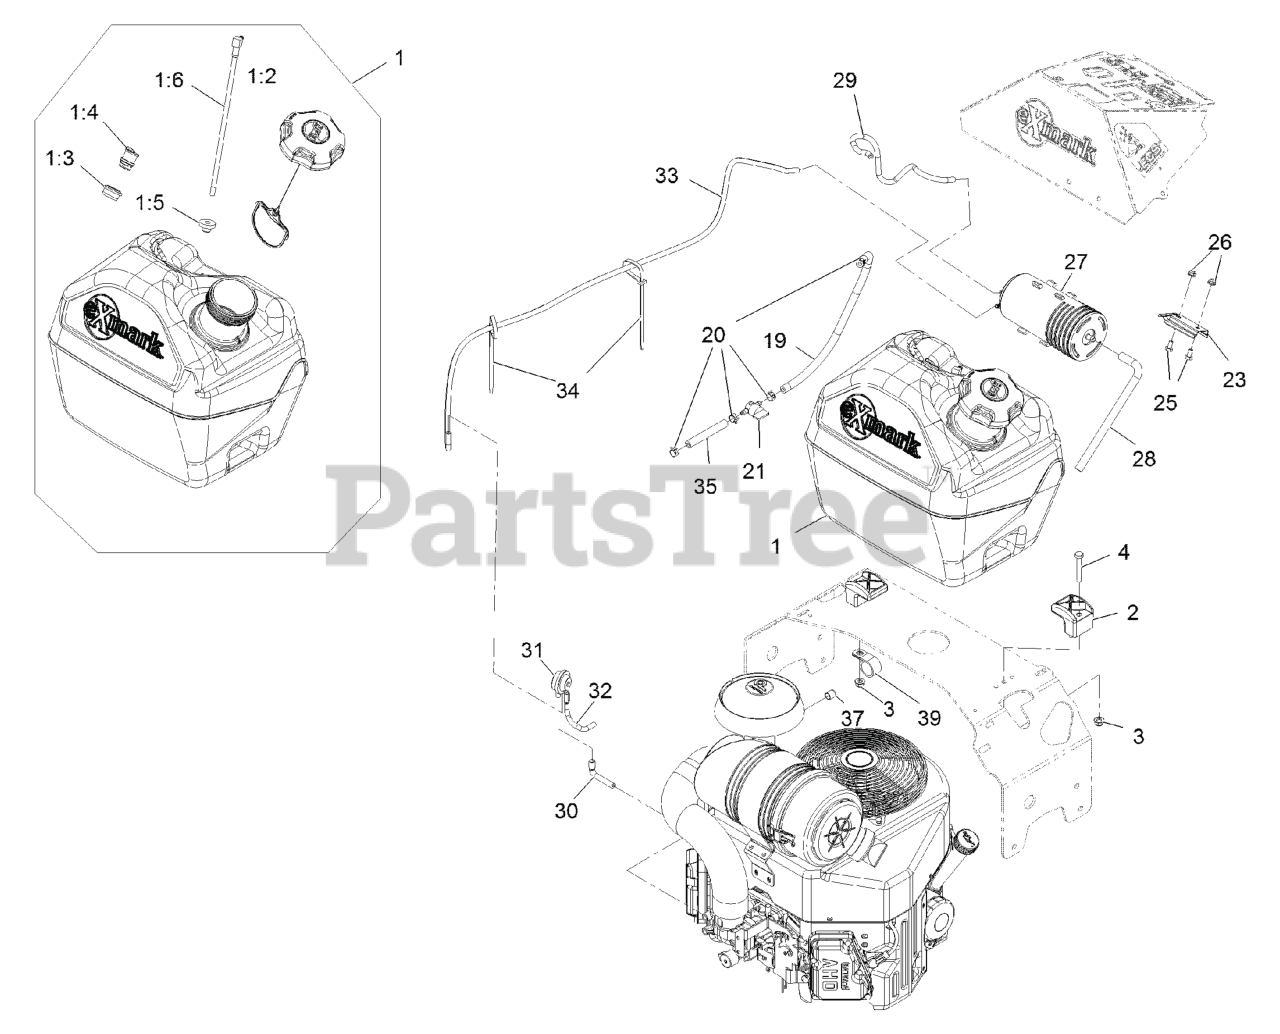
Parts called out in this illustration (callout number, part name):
1:2	CAP-FUEL, RATCHETING (3.5)
1:3	GROMMET
1:4	VALVE-VENT, FUEL
1:5	BUSHING
3	NUT-HF, NI
4	SCREW-HH
19	HOSE-FUEL
20	CLAMP-HOSE
21	VALVE-FUEL
22	BRACKET-CANISTER, CARBON
23	BRACKET-CANISTER, CARBON
24	SCREW-CARR
25	SCREW-HH
27	CANISTER-CARBON, 800CC
28	HOSE-VENT, CANISTER
29	HOSE-EMISSIONS
30	HOSE-VENT, FORMED
31	VALVE-CONTROL, VACUUM
32	HOSE-VENT, FORMED
33	HOSE-VENT, FORMED
34	TIE-PLASTIC
35	HOSE-FUEL
37	PLUG-PORT
39	CLIP-LOOM
